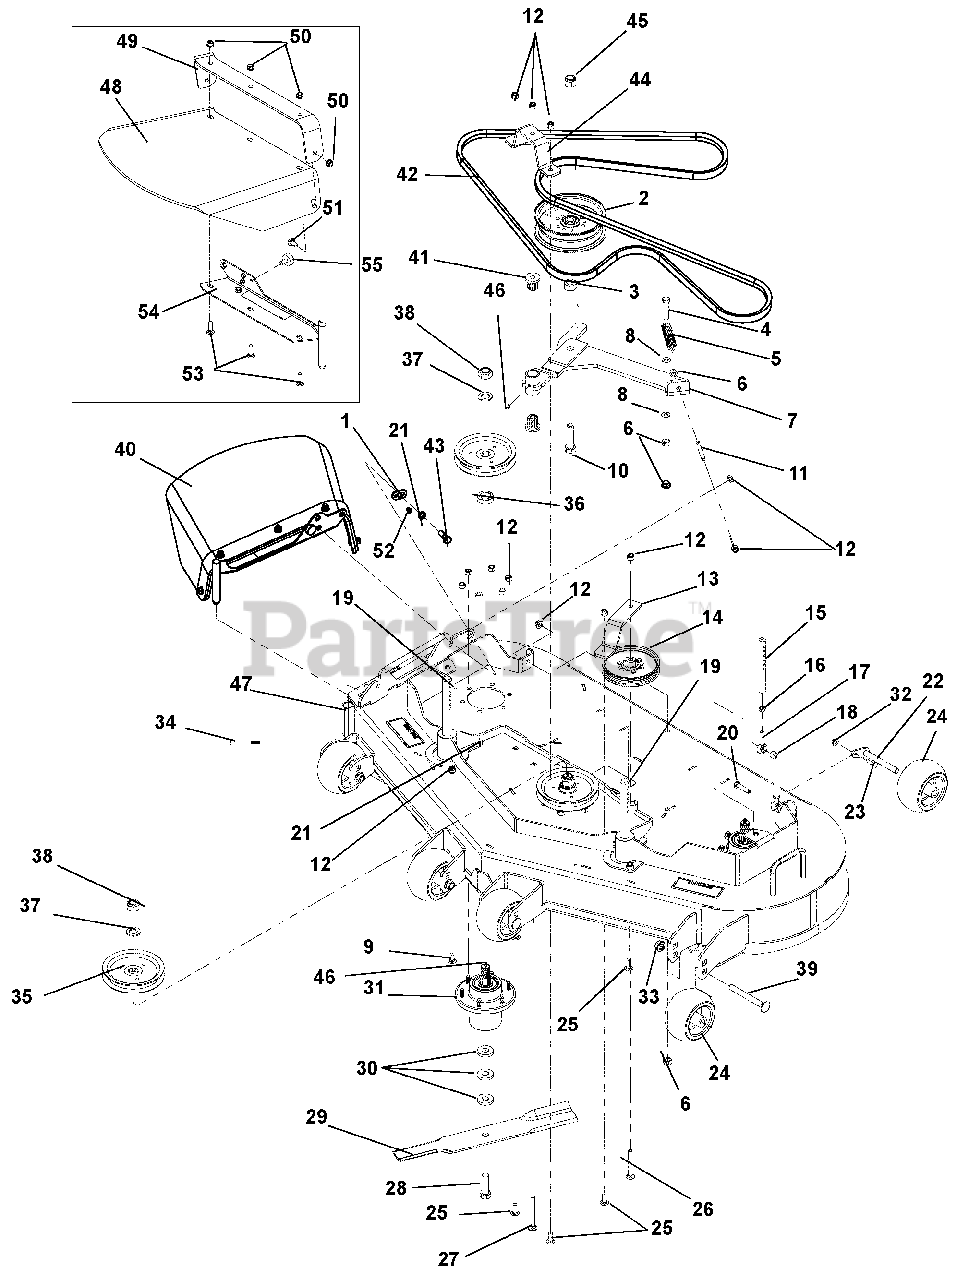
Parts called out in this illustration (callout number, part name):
1	KEEPER, BOLT
2	PULLEY, FLAT 6.00 X .635 W/BRG (988325)
3	BUSHING, .688 X 1.13 X .55 (988324)
4	BLT-HEX .38-16X1.75 GR5 YWZC
5	SPRING, EXT .875 X .125 X 4.25 Y
6	NUT, SPNLK-FLG .375-16
7	WLDT, IDLER ARM 48/52 FLOAT WALK
8	WASHER, FL-STL .406 X .812 X .065
9	BOLT, RDHDSHSQNK .38-16 X .75 G5
10	BOLT, HEX .62-11X2.50 GR5Y
11	ROD, THREADED ADJUSTMENT
12	NUT-LK-NYL .38-16
13	STRAP, IDLER 52/48 WALK
14	PULLEY, FLAT 5.00X.375 W/BRG
15	ROD, REAR HOC
16	NUT, JAM .375-24 YWZC REV
17	ROD, END 3/8 RH REV
18	BSHG - SLV REV
19	PIN, HOC
20	BLT-HEX .38-16X1.75 GR5 YWZC
21	WSHR-LK-EXT.391X.628X.036YWZC
22	PIVOT, RETAINER WELD
23	BOLT, RDHDSQNK .25-20 X 1.00 G5
24	ANTI-SCALP WHEEL - 5X3 CTR
25	BOLT, RDHDSQNK .38-16 X 1.00 G5
26	BOLT, RDHD SQNK .38-16 X 3.0 GR5YZ REV
27	BOLT, RDHDSQNK .38-16 X 3.50 GR5
28	BOLT, .62-11 X 2.00 HEX 8 Y
29	BLADE, 18.000 X .80 LIFT (988325)
29	BLADE, 16.500 X .80 LIFT (988324)
30	WASHER, FL-STL .630 X 1.50 X .25
31	ASSY, SPINDLE S/O
32	NUT, LK-NYL-FLG .25-20
33	NUT-LK-NYL-FLG .50-13
34	BOLT, 5/16-18 X 2.50 HEX 8
35	PULLEY, SPLINE SPINDLE SHFLWLK
36	SPACER, 1.500 X 1.000 X .510 Y
37	WASHER, .75 X 1.3125X .113
38	LOCKNUT, 3/4-16 CROWN GR 5
39	BOLT, RDHDSQNK .50-13 X 4.50 G5
40	ASSY, DISCHARGE SHIELD
41	BRG, FLG M10 X M25 X M27 FLUTED
42	BELT, HB 131.0 EL AMD (988325)
42	BELT, HB 124.8 EL (988324)
43	BLT, HEX.38-16X1.25 GR5 CAPTIVE
44	STRAP, IDLER 52 FLOAT WALK (988325)
44	STRAP, IDLER 48 FLWLK (988324)
45	NUT, LK-NYL .625-11 YWZC REV
46	FTG, 1/4-28 STRGT GREASE ZERK
47	ASSY, 52" FLOAT DECK W/DECALS (988325)
47	ASSY, 48" DECK W/ DECALS (988324)
48	SHIELD, WALK RUBBER DISCHARGE
49	STRAP, GRAVELY WLK RUBBER DIS
50	NUT, SPNLK-FLG .375-16
51	BOLT, RDHDSQNK .38-16 X 1.00 G5
52	RVT-POP .187 YZ
53	BOLT, RDHDSQNK .38-16 X 1.25 G5
54	WLDT. DISCHARGE
55	BUMPER, RUBBER
